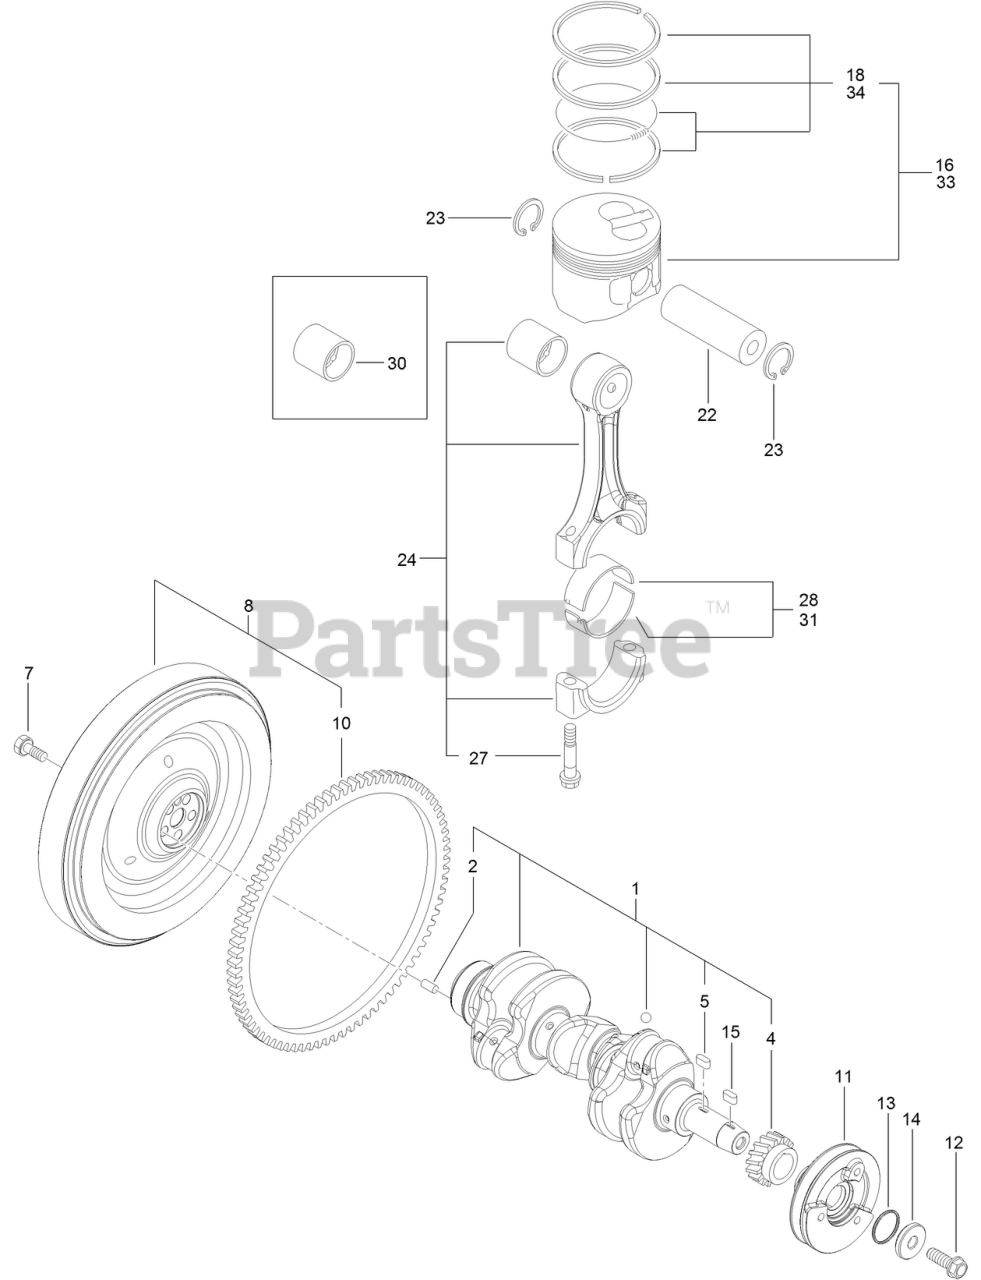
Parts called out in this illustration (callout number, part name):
1	CRANKSHAFT ASM
4	GEAR-CRANKSHAFT
8	FLYWHEEL ASM
11	V-PULLEY, CRANKSHAFT 1
12	BOLT, FLANGE 12X1.25 1
13	PACKING-WASHER
14	WASHER
16	PISTON ASM
18	RING ASM
22	PIN-PISTON
24	CONNECTING ROD ASM
27	BOLT-CONNECTING ROD
28	BEARING-CRANK PIN
30	BUSHING-PIN, PISTON
31	BEARING, PIN 0.25
33	PISTON ASM (0.25 OS)
34	RING ASM
